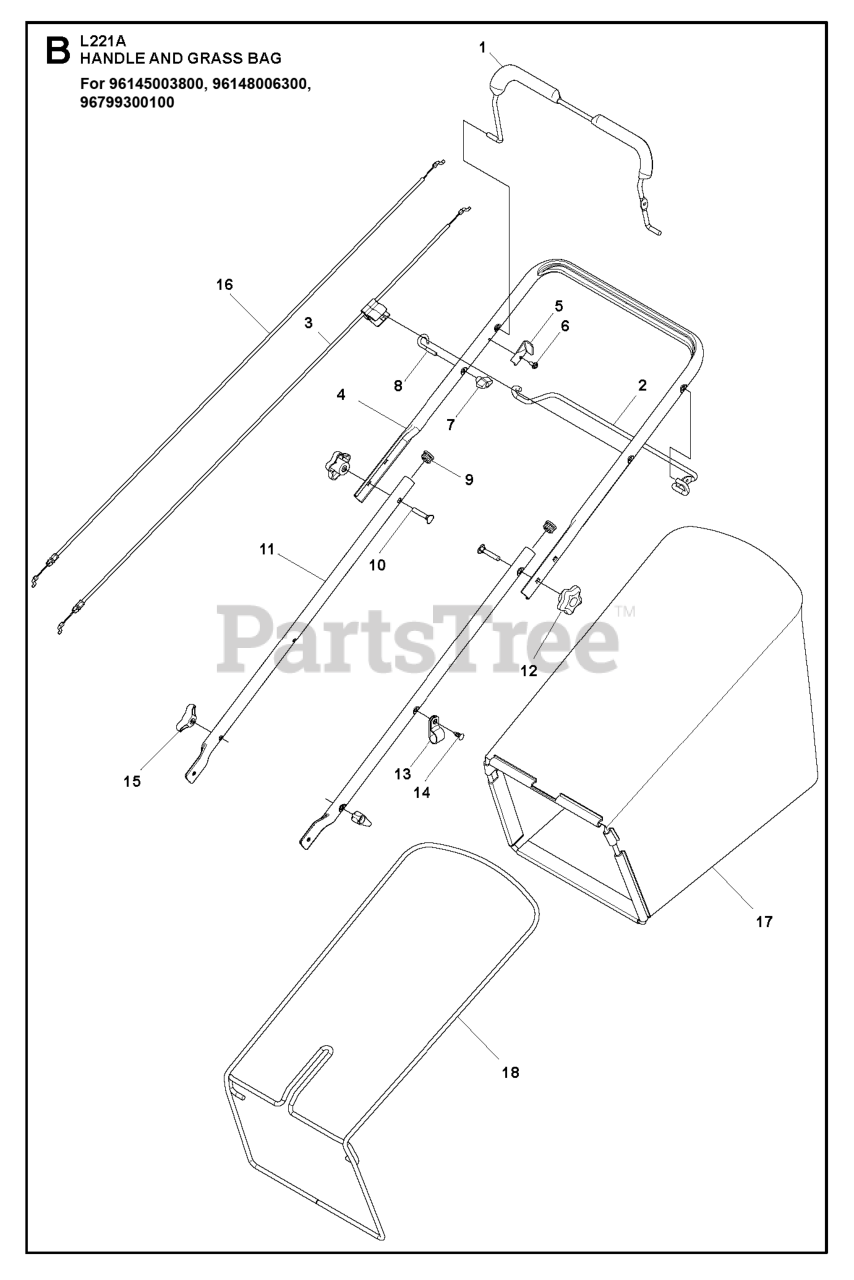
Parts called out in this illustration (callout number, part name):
1	BAIL.ARM.ASSY:STRAIGHT OM
2	BAIL.CONT.DR.S/S.ROUND.BLACK
3	CABLE.MZR.RGD.PLUS.STRT
4	HANDLE.UPP.DST.EXTCR.SM.SP.498
5	BRACKET.UPSTOP.RT
6	SCREW
7	T-KNOB.NEW ROPE GUIDE
8	GUIDE.ROPE.BLK.ZINC.CHROM
9	PLUG.PLASTIC.7/8".14-20.GAUGE
10	BOLT.CONCAVE.HEAD.RETAINING
11	HANDLE.LOW.2PC.2POS.21EFF.498
12	KNOB.HANDLE.PLASTIC.STAR.BLACK
13	CLIP.CABLE.BLK
14	FASTENER.PUSH.O.250X0.783
15	KNOB, DEFLECTOR
16	CABLE.DRIVE.UB.NA.21EFF.AW
17	GBAG.C361029EM.HUSQ.GRY.21EFF
18	FRAME.GBAG.AWD.21.BLACK
